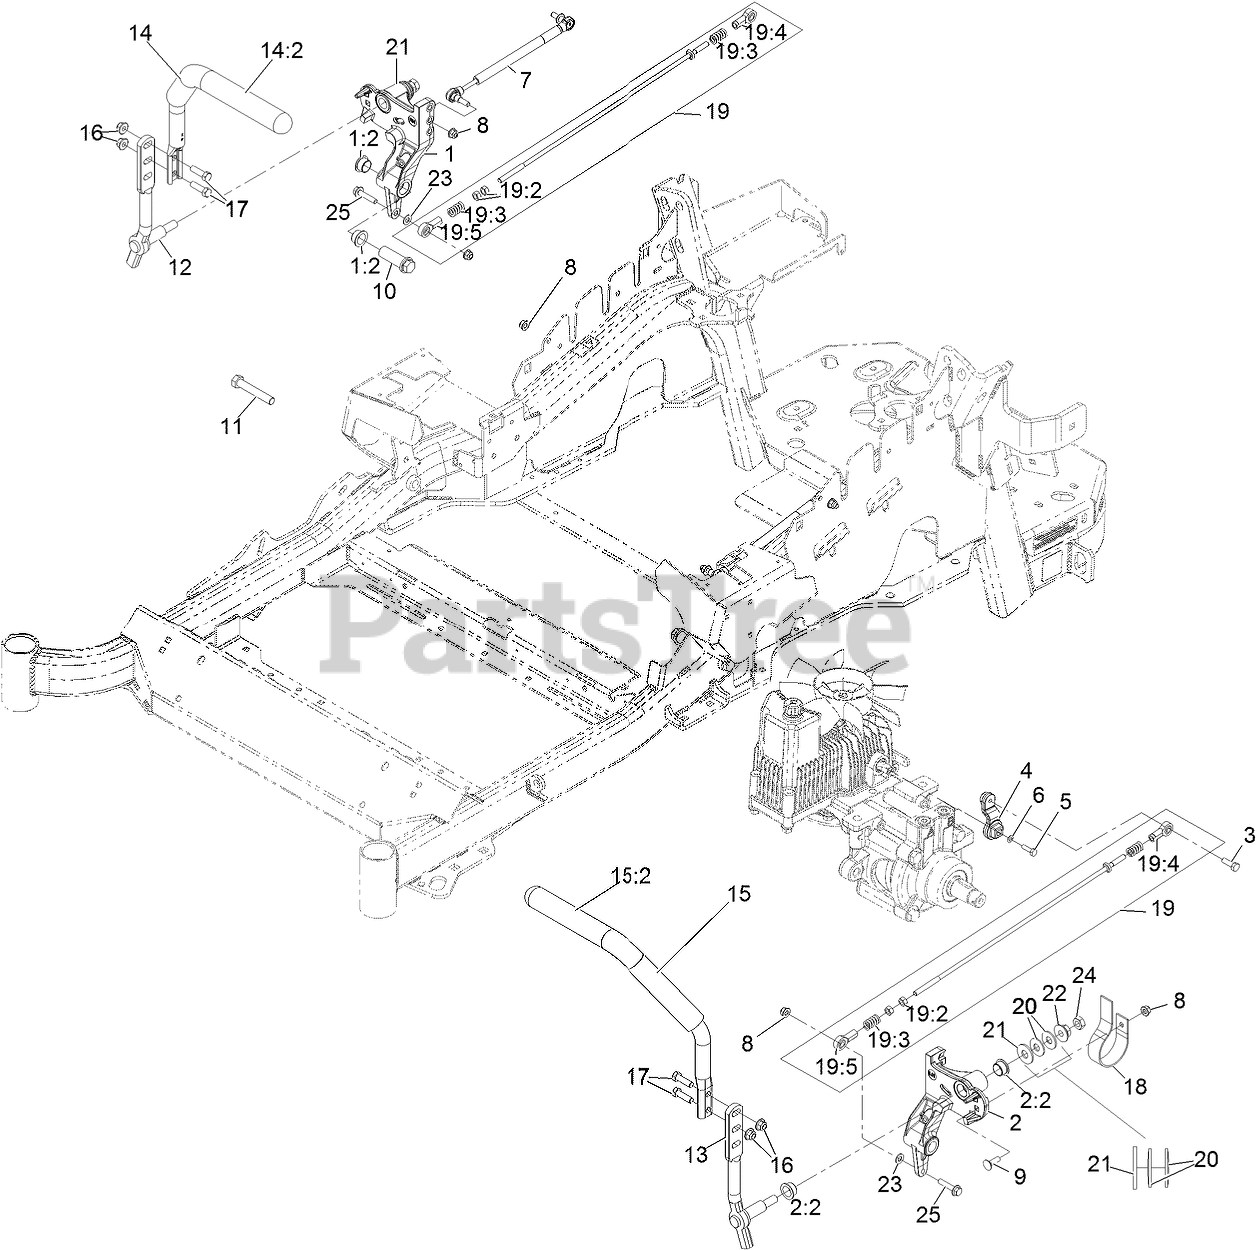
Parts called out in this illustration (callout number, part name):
1	RH MOTION CONTROL AND BUSHING ASM
1:2	BUSHING-FLANGE
2	LH MOTION CONTROL AND BUSHING ASM
2:2	BUSHING-FLANGE
3	SCREW-HH, THREAD LOCKING
4	ARM-CONTROL, PUMP
5	SCREW-HH
6	WASHER-SPRING
7	DAMPER-CONTROL, MOTION
8	NUT-HF, NI
9	BOLT-CARR
10	HUB-THREADED
11	SCREW-HH
12	LEVER-CONTROL MOTION, RH
13	LEVER-CONTROL MOTION, LH
14	RH HANDLE ASM
14:2	LH HANDLE ASM
15	GRIP-LEVER, CONTROL
15:2	NUT-HF, NI
16	SCREW-HH
17	SPRING-LEAF
18	PUMP LINKAGE REAR ASM
19	NUT-HEX
19:2	SPRING-COMPRESSION
19:3	BALLJOINT-LH
19:4	BALLJOINT-RH
19:5	WASHER-SPRING
20	WASHER-FLAT
22	WASHER-PLAIN
23	NUT-JAM
24	SCREW-HHF
25	SCREW-HHF
